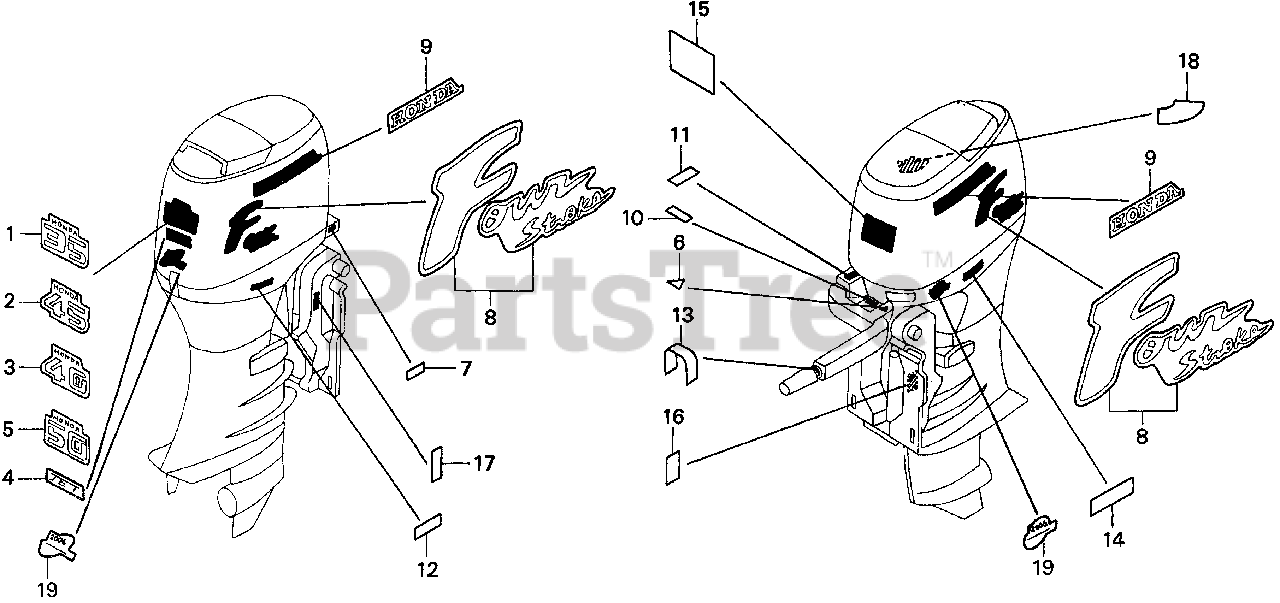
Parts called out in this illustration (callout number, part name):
8	MARK, R. SIDE STRIPE
9	MARK, SIDE STRIPE
10	LABEL, SPECIFICATION
12	LABEL, OIL CAUTION (E)
14	LABEL, STORING CAUTION (ENGLISH)
15	LABEL, CAUTION OPERATOR (ENGLISH)
18	MARK, EMERGENCY START (ENGLISH)
